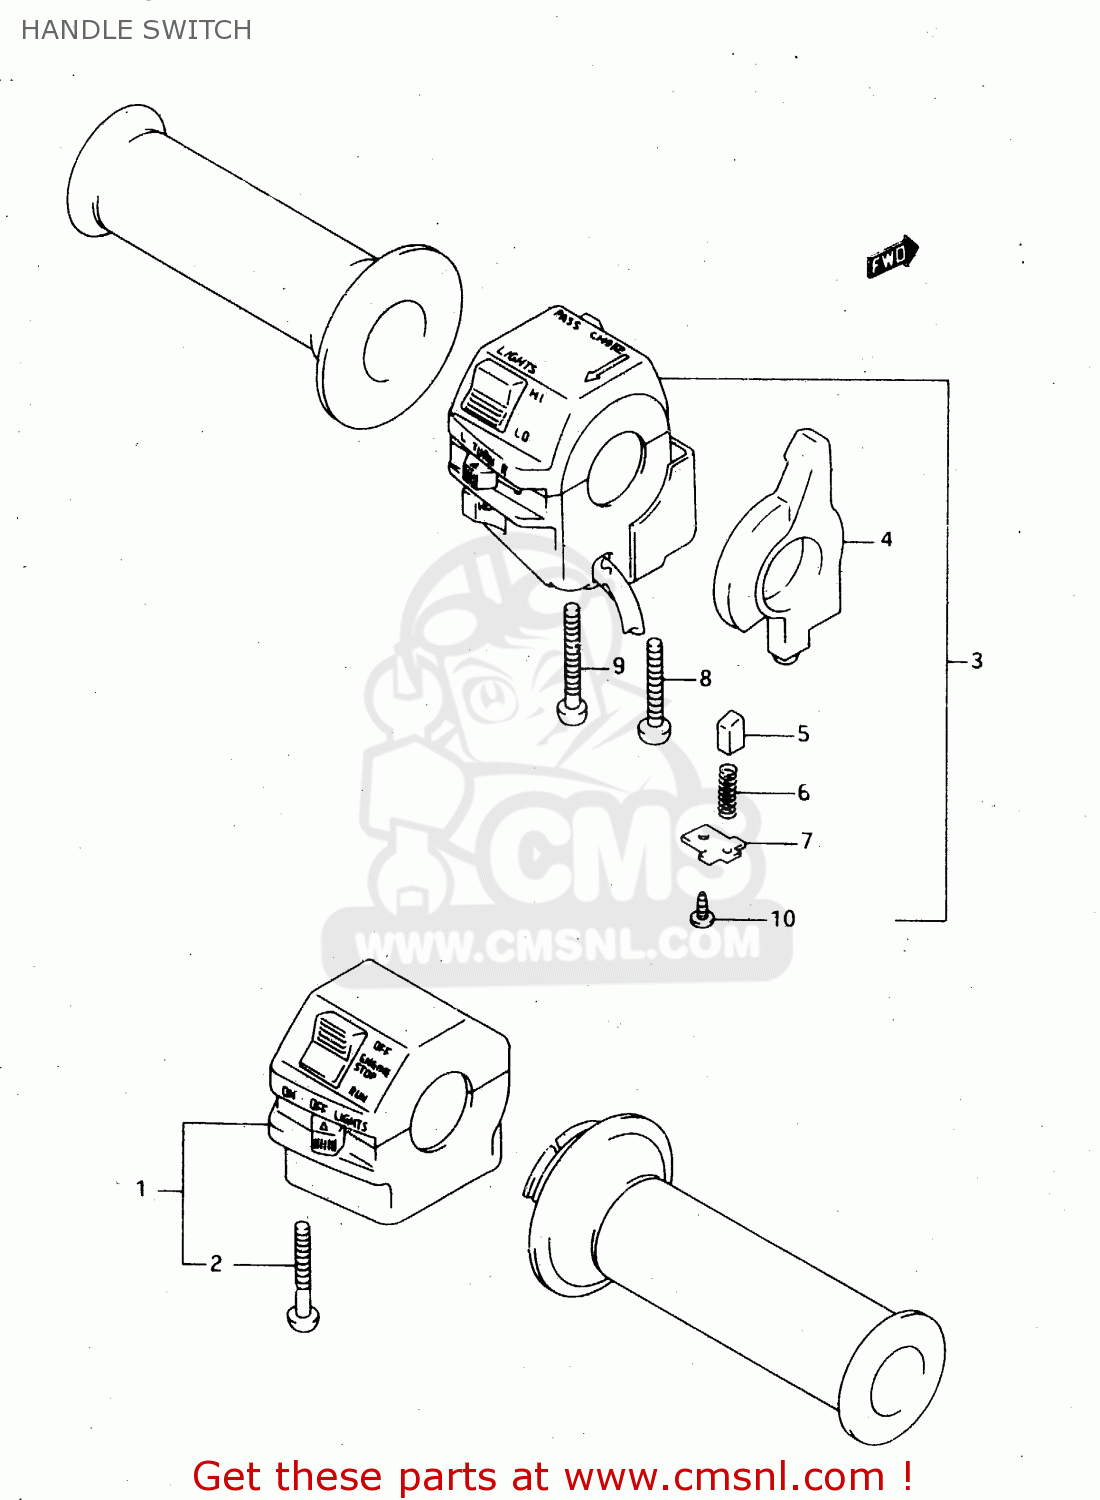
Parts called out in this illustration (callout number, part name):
1	SWITCH ASSY, HANDLE RH
2	SCREW, 5X45
3	SWITCH ASSY
4	LEVER,CHOKE
5	PIECE,SLIDE
6	SPRING
7	PLATE
8	SCREW
9	SCREW, 5X45
10	SCREW, TRUNK BOX
